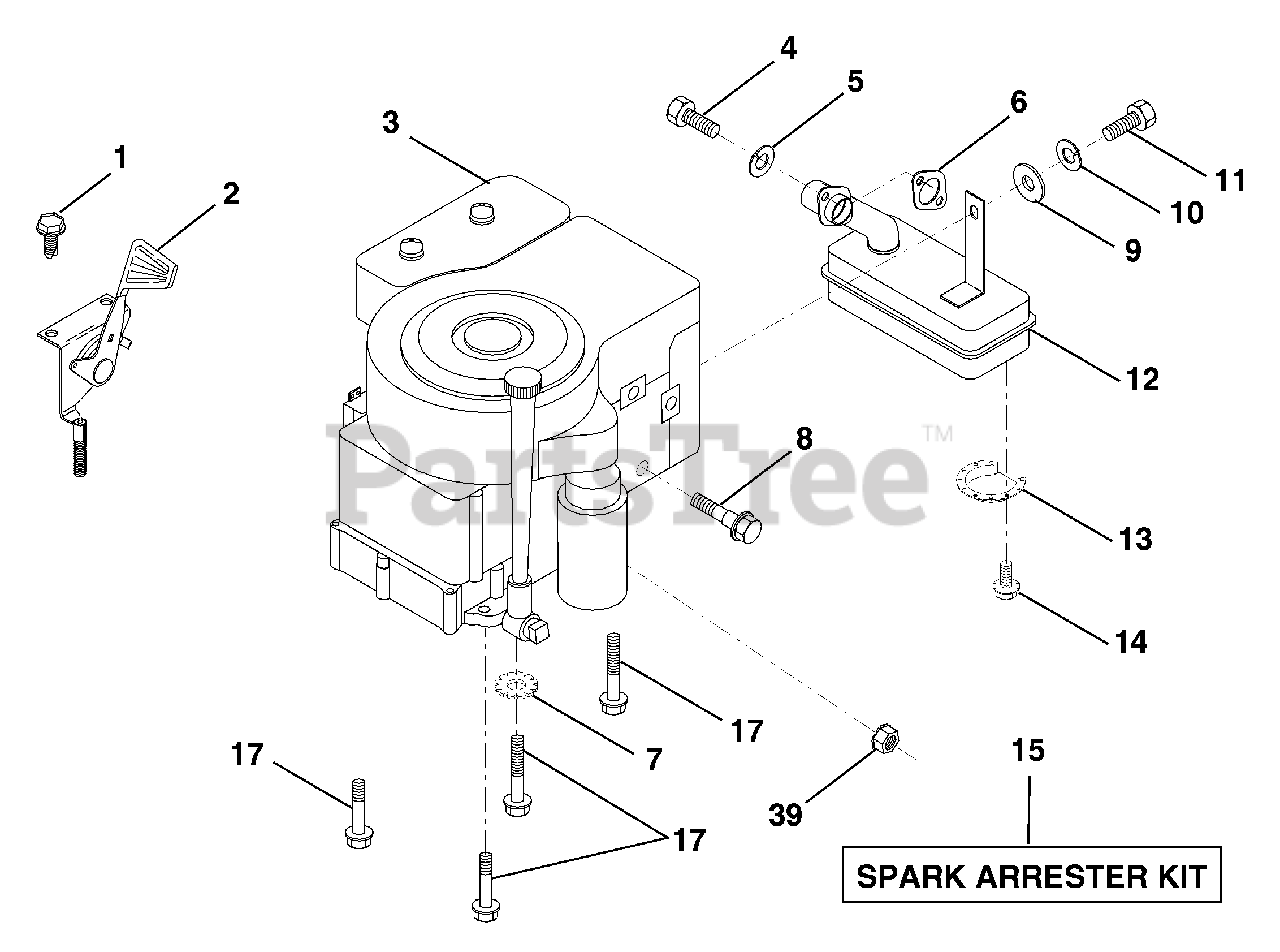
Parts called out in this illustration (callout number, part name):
1	Screw, Hex Thd. Cut 1/4-20 x 1/2
2	Control, Throttle
3	Engine
4	Screw, Hex, Cap 5/16-18 x 3/4
5	Washer, Lock Hvy Hcl Spring 5/16
6	Gasket, Exhaust
7	Washer Lock Ext. Tooth 3/8
8	Bolt, Shoulder 5/16
9	Washer 5/16 x 3/4 x 16
10	Washer, Lock Hvy Hlcl Spring 1/4
11	Bolt, Hex Fin.
13	Deflector, Muffler
14	Screw, Spiderlock, Hex Hd 8 x 1/2
15	Arrester, Spark
17	Screw, Hex Washer Head, Thdrol. 3/8-16 x 1-1/2
39	Nut, Flange 1/4-20
